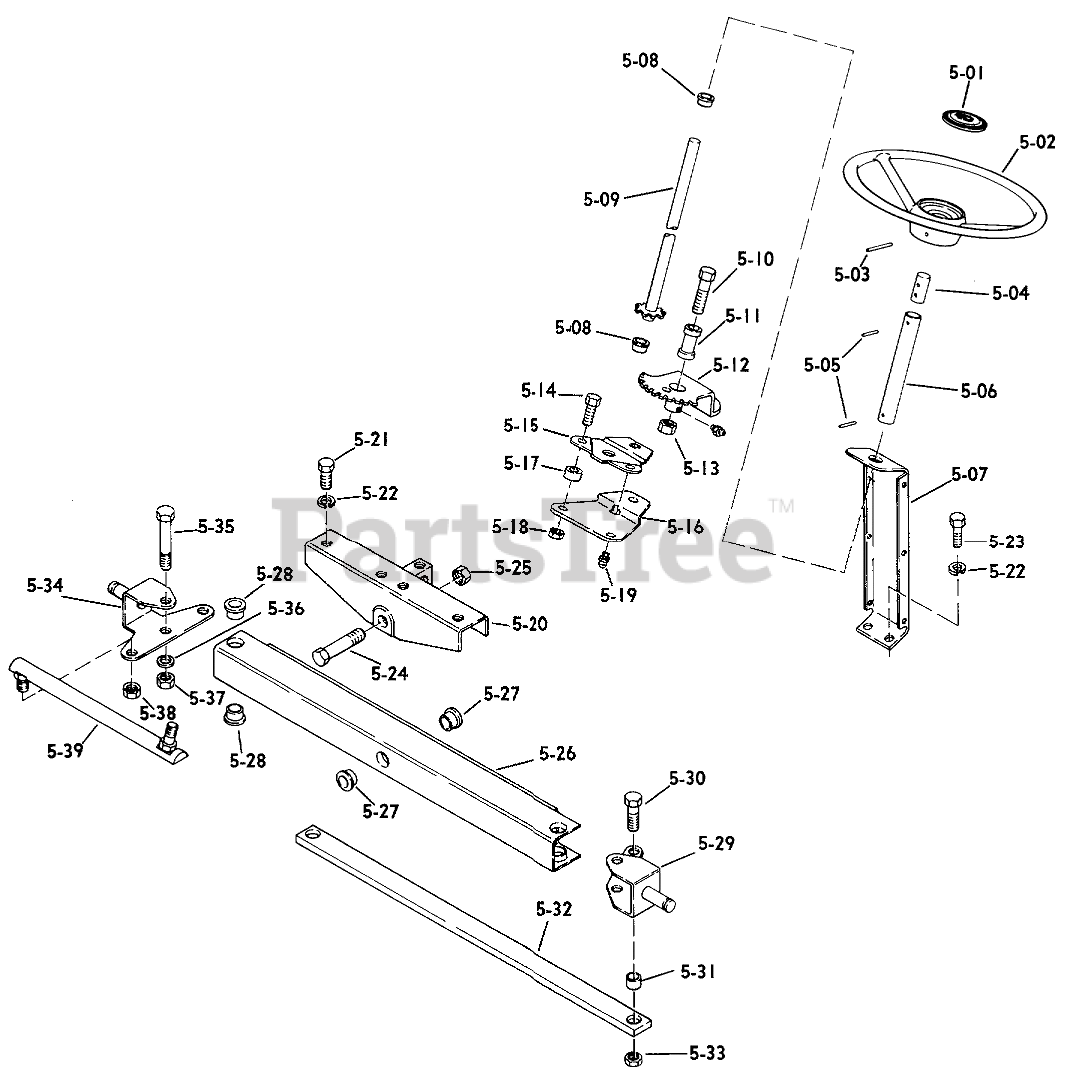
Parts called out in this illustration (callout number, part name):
5-01	STEERING WHEEL INSE
5-02	STEERING WH 13" SOFT
5-03	Roll Pin 1/4 x 2 1/2
5-04	Adapter-Steering Wheel
5-05	SPIROL ROLL PIN
5-06	Steering Tube
5-07	Steering Support
5-08	BEARING
5-09	Steering Shaft
5-10	Bolt 1/2-13 x 2 3/4
5-11	Bushing
5-12	Steering Sector
5-13	Eslok Nut
5-14	Bolt
5-15	Steering Gear Support
5-16	Steering Support
5-17	Spacer
5-18	Nut
5-19	Zerk
5-20	Axle Support
5-21	Bolt, 3/8-16 x 1/2
5-22	LOCKWASHER
5-23	Bolt
5-24	Bolt
5-25	Eslok Nut
5-26	Front Axle
5-27	BUSHING
5-28	Bushing
5-29	Ass-y. Arm & Spindle L.H.
5-30	BOLT
5-31	SPACER
5-32	Drag Link
5-33	NUT
5-34	R.H. Arm & Spindle Assembly
5-35	Bolt-Shoulder
5-36	WASHER
5-37	NUT
5-38	NUT-6
5-39	Ball Joint
